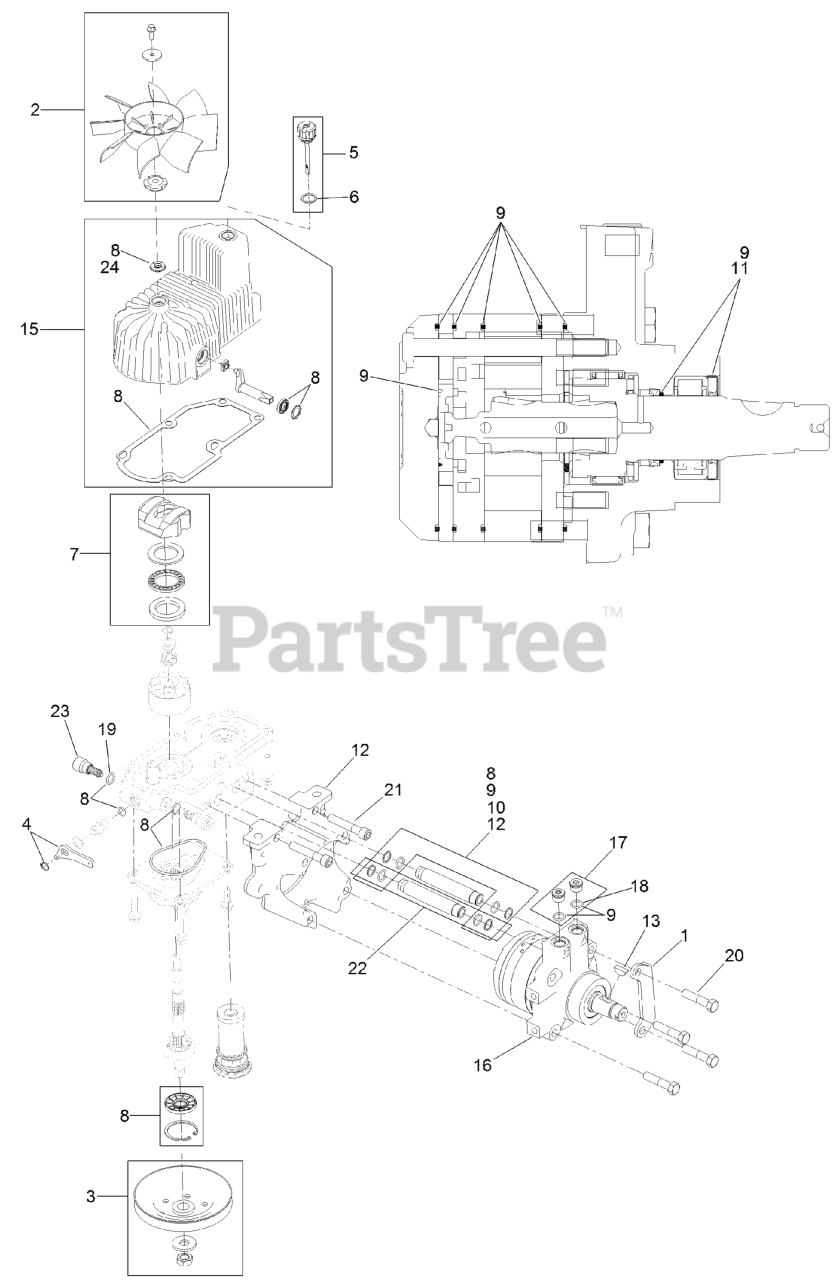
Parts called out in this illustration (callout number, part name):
1	MOUNT-SHOE, HORSE
2	FAN KIT
3	PULLEY KIT
4	HANDLE-BYPASS VALVE, HYDRO
5	DIPSTICK-HYDRO W/GASKET
6	GASKET-DIPSTICK, HYDRO
7	SWASH BLOCK KIT
8	PUMP SEAL KIT
9	MOTOR SEAL KIT
10	TUBE SEAL KIT
11	OUTPUT SHAFT SEAL KIT
12	NOSE CUP-UHT
13	KEY-WOODRUFF
15	HOUSING-HYDRO, RH
16	MOTOR-HYDRAULIC, RH 280CC
17	MAGNETIC PLUGS SERVICE KIT
19	O-RING-CHECK VALVE
20	SCREW HH
21	SCREW-HSH
22	HYDRAULIC TUBE KIT
23	SHOCK VALVE, 16CC HYDRO
24	SEAL-FAN DRIVE
25	Kit, Pump Section 16Cc RH
26	Kit, Rotating Grp 16Cc RH
99	PULLER-PULLEY
